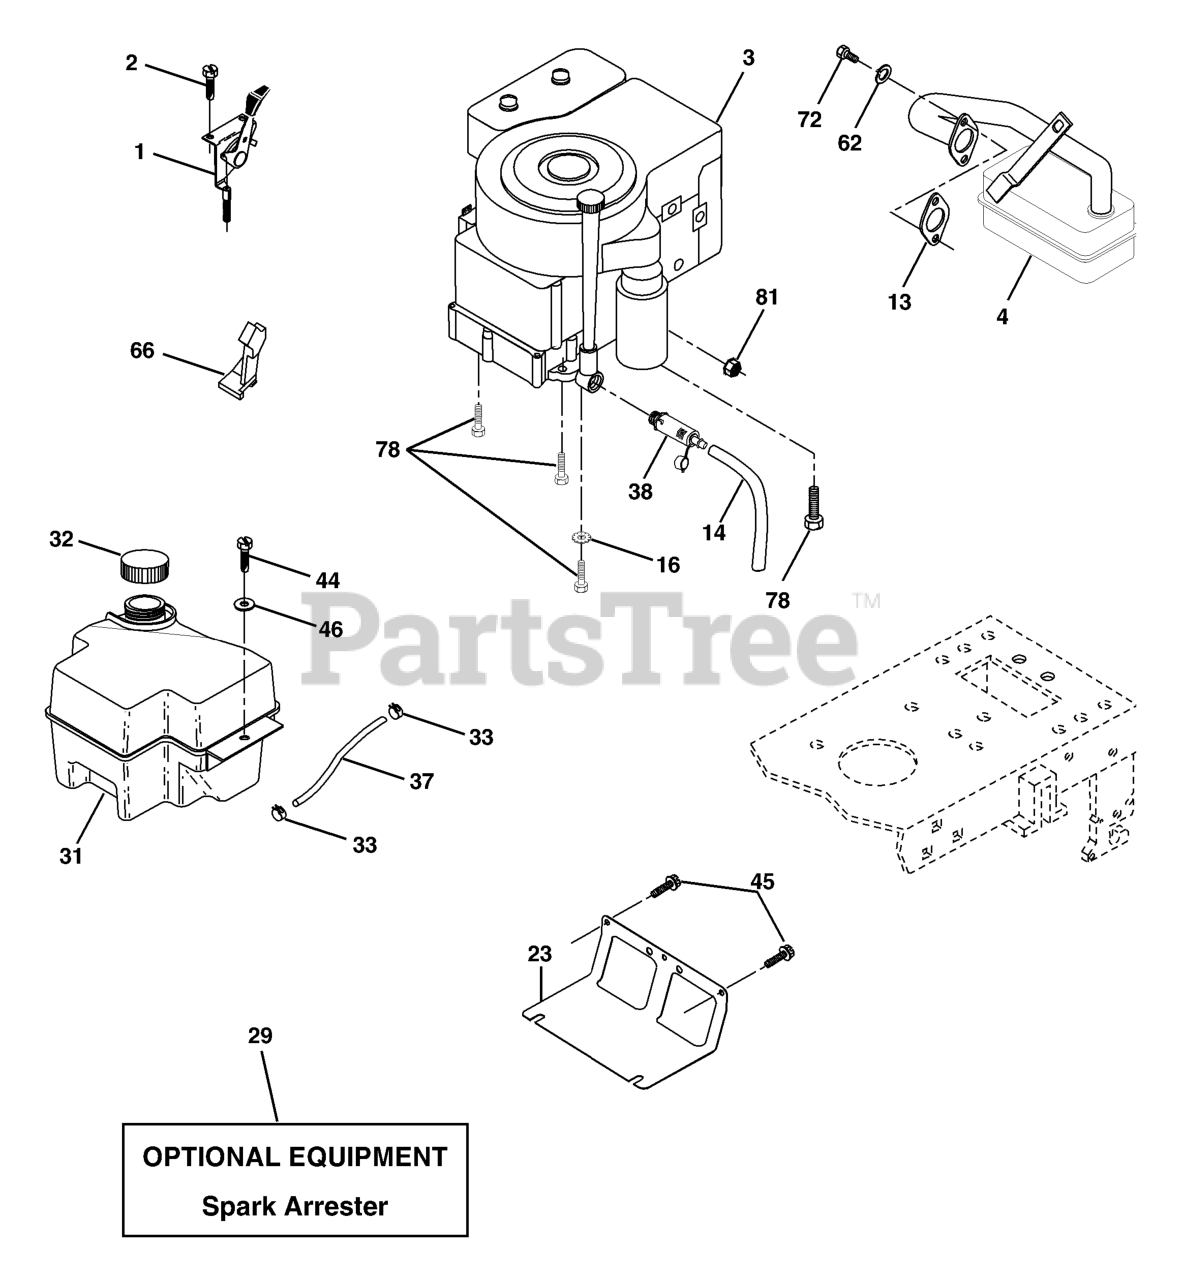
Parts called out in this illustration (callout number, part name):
1	THROTTLE.CONTROL.CABLE.BLACK
2	SCREW LT
4	MUFFLER.SINGLE.B&S.10-12HP
13	REPL BY 532 27 22-93
14	TUBE, DRAIN OIL ASM.
16	LOCKWASHER
23	SHIELD.BROWNING.DBR.GUARD
29	KIT.SPARK ARRESTOR 794945 B&S
31	FUEL TANK
32	FUEL CAP
33	HOSE CLAMP
37	LINE.FUEL.20
38	PLUG, OIL DRAIN EASY
44	SCREW HEX CRT
45	SCREW, 3/8-16X3/4
46	WASHER
62	WASHER.LOCK.HVY.HLCL.SPR.5/16
66	STOP THROTTLE
72	SCREW
78	SCREW.3/8-16
81	NUT
